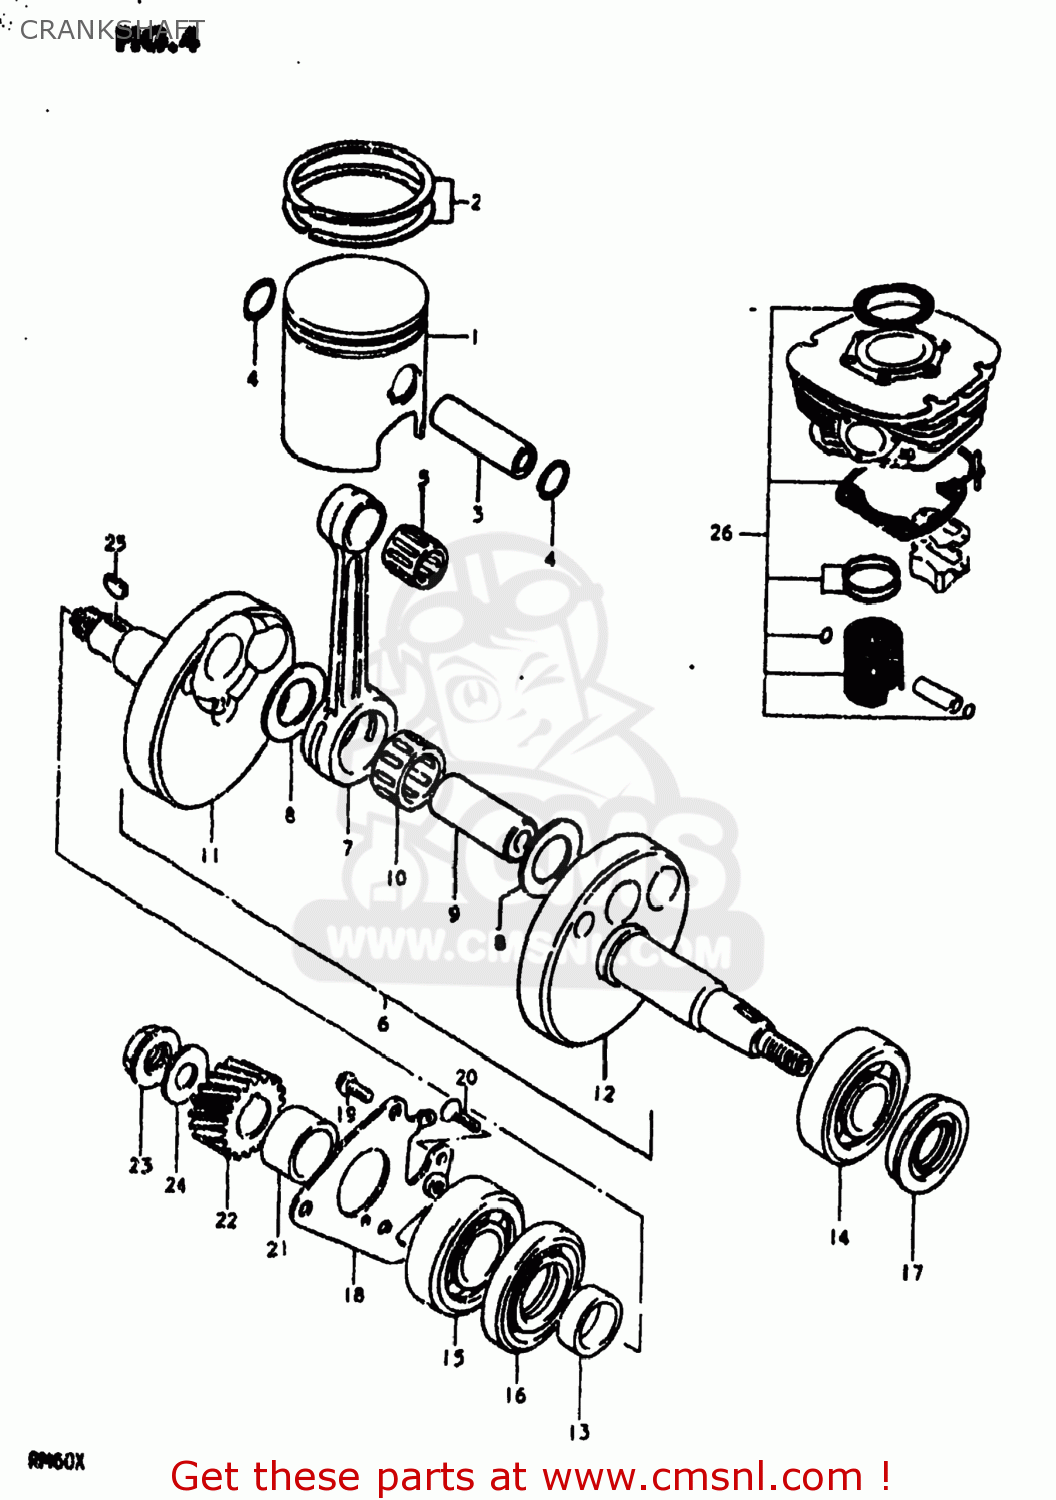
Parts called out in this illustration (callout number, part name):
1	PISTON
2	RING SET,PISTON
3	PIN,PISTON
4	RING,SNAP
5	BEARING
6	CRANKSHAFT ASSEMBLY
7	CONNECTING ROD
8	WASHER
9	PIN,CRANK
10	BEARING
11	CRANKSHAFT
12	CRANKSHAFT,LEFT
13	SPACER(20X26X9)
14	BEARING
15	BEARING
16	OIL SEAL
17	OIL SEAL
18	RETAINER
19	SCREW 6X12
20	SCREW
21	SPACER(20X26X14)
22	GEAR,PRIMARY DRIVE NO.19
23	NUT
24	WASHER
25	KEY
26	PISTON SET
